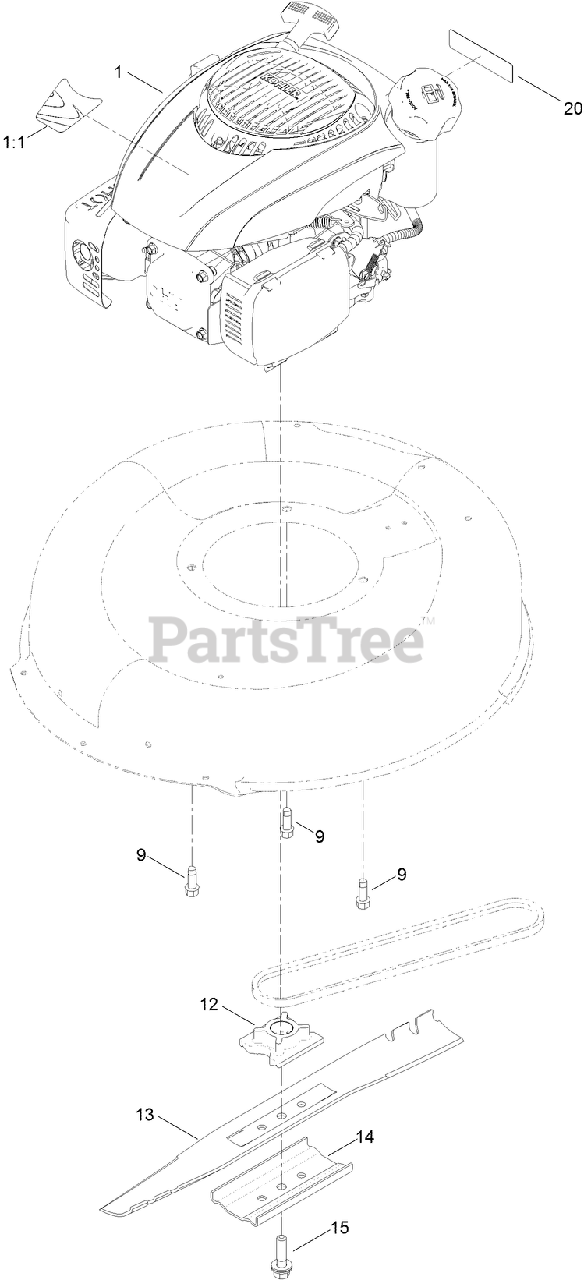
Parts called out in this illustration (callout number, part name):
1:1	DECAL-SHROUD
9	SCREW-TAPTITE
12	RETAINER-BLADE
14	SUPPORT-BLADE
15	BOLT-BLADE
20	DECAL-ARRESTER, SPARK
